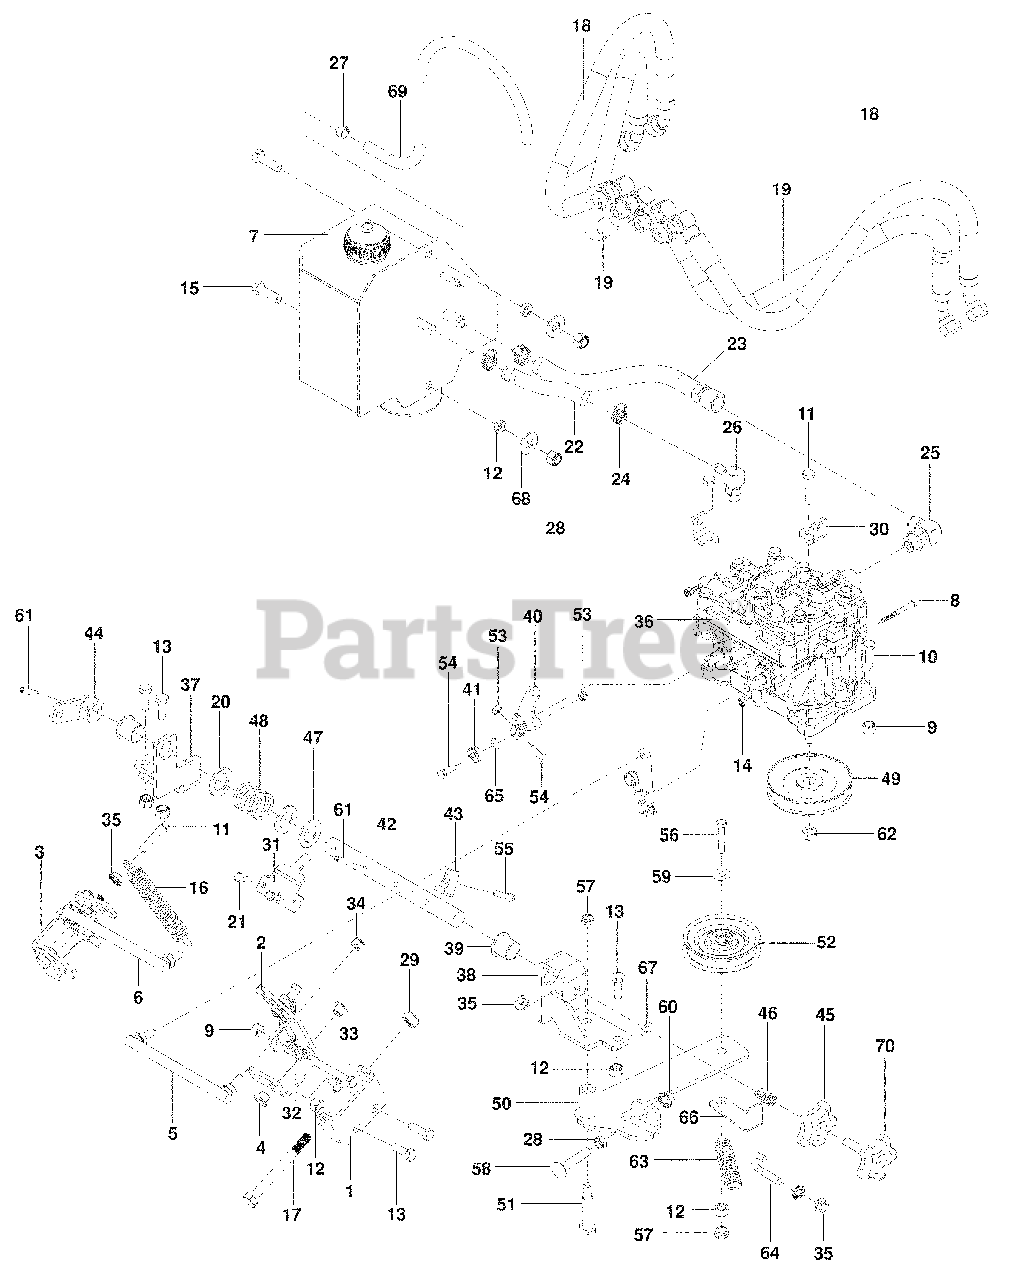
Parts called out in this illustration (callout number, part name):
2	BELLCRANK, RH
3	BELLCRANK, LH
4	BEARING, FLANGE
5	LINK, CONTROL, RH
6	LINK, CONTROL, LH
8	SCREW #10-24 SCKT HD
9	NUT 5/16-18 HEX NYLOC
10	HCS 5/16-18 x 1¼
11	HCS 5/16-18 x 1½
12	NUT 3/8-16 HEX NYLOC
13	Hcs 3/8-16 x 7/8
14	NUT #10-24 HEX NYLOC
15	HCS 3/8-16 x 1¼
17	HCS M10-1.5 x 100 GR 8.8
20	WASHER, FIBER
21	HCS M6-1.0 x 16MM GR 8.8
22	HOSE, RETURN
23	HOSE, SUCTION
24	CLAMP, HOSE
25	ELBOW 90°
26	FITTING 90°
28	Nut 3/8-16 Hex Jam
29	NUT, M10-1.5 NYLON RING
30	BRACKET, SPRING
31	PLATE, NEUTRAL STOP
33	HCS 5/16-18 x 2
34	NUT M8 x 1.25 NYLOC
35	NUT 5/16-18 HEX WHIZLK
36	PUMP, DUP10S
37	SUPPORT, CAM LH
38	SUPPORT, CAM RH
39	BEARING, FLANGE
40	ARM, HYDRO
41	BEARING, FOLLOWER
42	SHAFT, CAM
43	CAM, TRACKING
44	ARM, SPEED CONTROL
46	SPRING, COMPRESSION
47	WASHER, 20MM
48	SPRING, COMPRESSION
49	PULLEY, PUMP
50	ARM, IDLER
51	BOLT, SHOULDER
53	NUT ¼-20 HEX THIN NYLOC
54	HCS ¼-20 x ¾
55	HCS M6-1.0 x 30MM GR 8.8
56	HCS 3/8-16 x 2
57	NUT 3/8-16 HEX JAM NYLOC
58	RHSNB 3/8-16 x 2
59	WASHER 3/8 SAE FLAT
60	NUT 3/8-16 HEX WHIZLK
61	ROLL PIN, 6 MM x 30 MM
62	NUT, M10-1.5 L/H HEX
66	KEEPER, BELT
67	WASHER 5/16 SAE FLAT
68	WASHER 3/8 FLAT
70	KNOB, ADJUSTMENT
